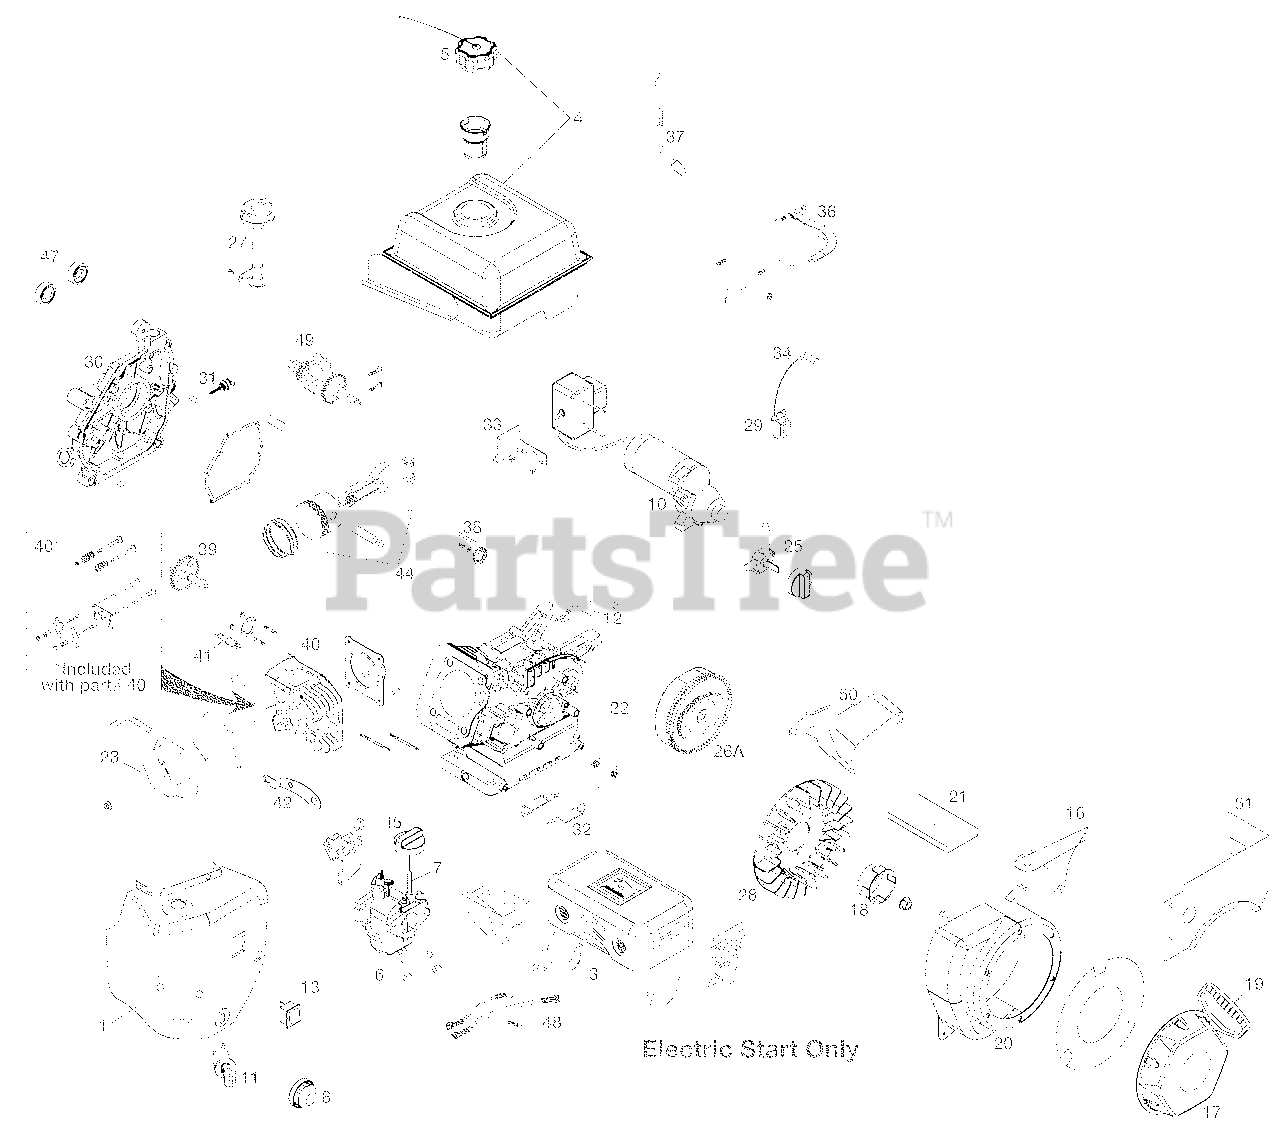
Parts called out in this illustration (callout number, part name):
1	HEATER BOX ASSEMBLY-SNOW
3	MUFFLER ASSEMBLY-SNOW
4	FUEL TANK ASSEMBLY-SNOW
5	FUEL TANK CAP-OVERSIZED (CLICK STYLE)-SNOW
6	CARBURETOR ASSEMBLY-SNOW
7	CHOKE LEVER,CARBURETOR-SNOW
8	PRIMER BULB ASSEMBLY W/HOSE-SNOW
10	ELECTRIC STARTER ASSEMBLY-SNOW
11	KEY SWITCH ASSEMBLY-SNOW
12	CDI BOX ASSEMBLY-SNOW
13	ON/OFF SWITCH-SNOW
15	CHOKE KNOB-SNOW
16	GOVERNOR LINKAGE SHIELD PLATE-SNOW
17	RECOIL STARTER ASSEMBLY-SNOW
18	STARTER CUP SMALL-SNOW
19	STARTER GRIP-SNOW
20	BLOWER HOUSING ASSEMBLY, ELECTRIC START-SNOW
21	SHIELD, CYLINDER
22	SHIELD, UNDER FLYWHEEL CHARGING SYSTEM-SNOW
23	VALVE COVER
25	FUEL PETCOCK, SNOW
26	FLYWHEEL ASSEMBLY, ELECTRIC START-SNOW
26A	FLYWHEEL ASSEMBLY, MANUAL START-SNOW
27	HIGHOIL FILL ASSY KIT, SOW
28	FLYWHEEL FAN
29	IGNITION COIL ASSY
30	CRANKCASE COVER ASSY
31	NON-REMOVABLE OIL PLUG
32	CHARGING COIL AC/DC
33	ELECTRIC STARTER BRACKET
34	SPARK PLUG BOOT
36	GOVERNOR ARM ASSY
37	GOVERNOR SHAFT
38	GOVERNOR GEAR ASSEMBLY
40	CYLINDER HEAD ASSY
41	SPARK PLUG
42	CDI BOX BRACKET-SNOW
44	PISTON AND ROD ASSY
46	VAPOR SHIELD
48	WIRE HARNESS
49	CRANKSHAFT
50	TOP SHIELD
51	FUEL TANK SKIRT
